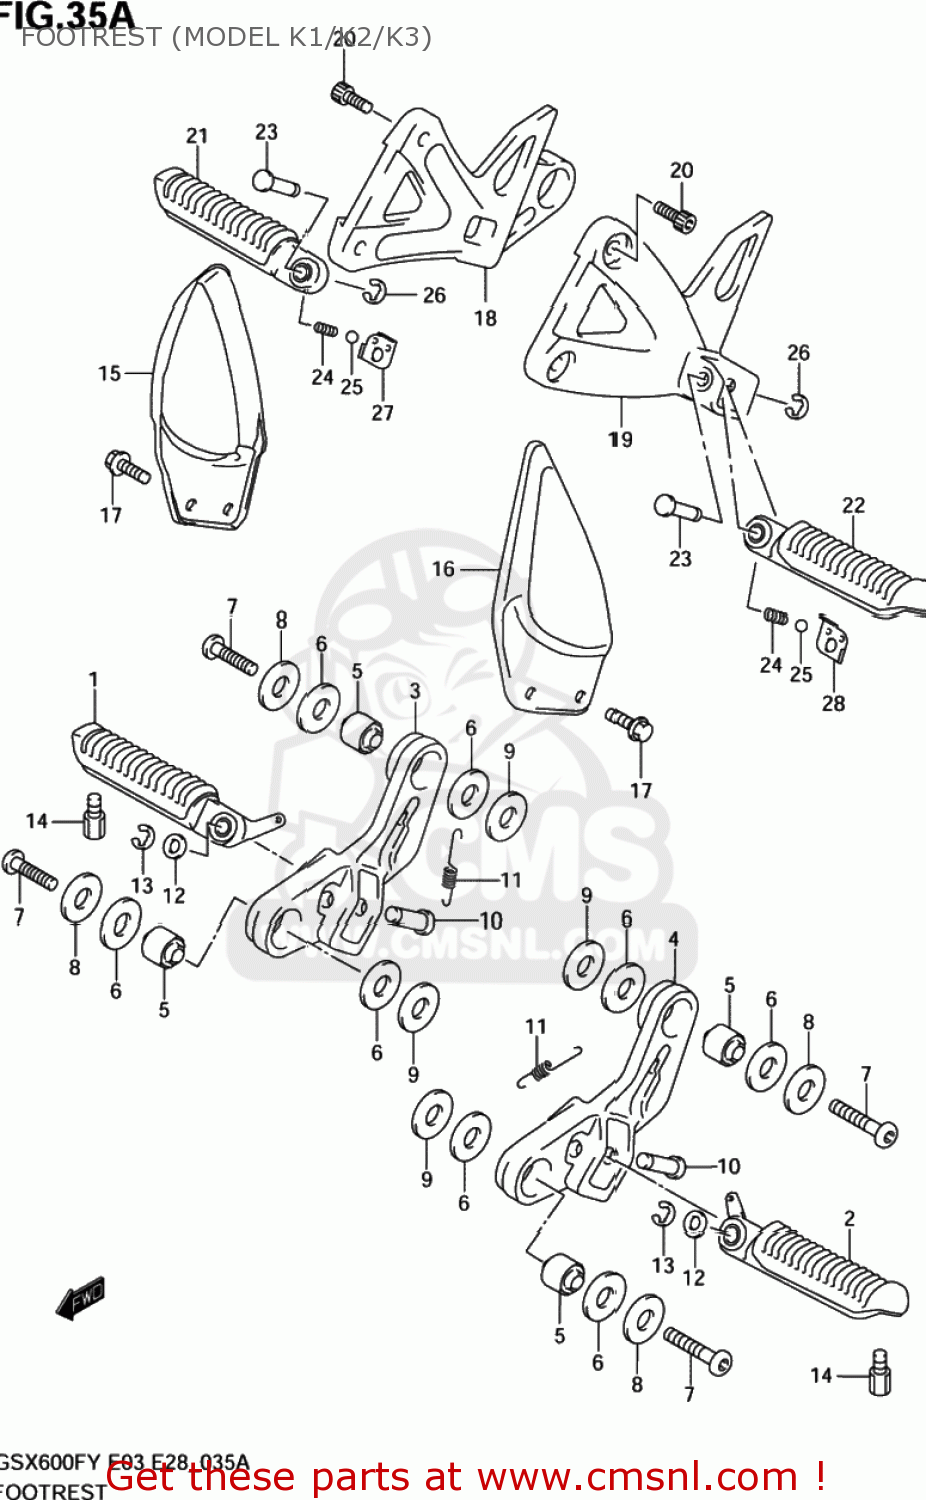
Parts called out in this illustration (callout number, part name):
1	BAR,FRONT FOOTREST,RIGHT
2	BAR,FRONT FOOTREST,LEFT
3	HOLDER,FR FOOTREST,R
4	HOLDER,FR FOOTREST,L
5	BUSH(8.4X20X18)
6	WASHER(12.5X30X2)
7	BOLT(8X33)
8	WASHER (8.5X30X2.3)
9	WASHER(8.5X30X2.3)
10	PIN(8X33.2)
11	SPRING
12	WASHER
13	E.RING
14	BOLT,BANK SENSOR
15	GUARD,FR FOOTREST,R
16	GUARD,FR FOOTREST,L
17	BOLT(8X16)
18	BRACKET,PILLION FOOTREST,R
19	BRACKET,PILLION FOOTREST,L
20	BOLT(8X23)
21	BAR,PILLION FOOTREST,R
22	BAR,PILLION FOOTREST,L
23	PIN
24	SPRING
25	BALL
26	E.RING
27	PLATE,PILLION FOOTREST,R
28	PLATE,PILLION FOOTREST,L
